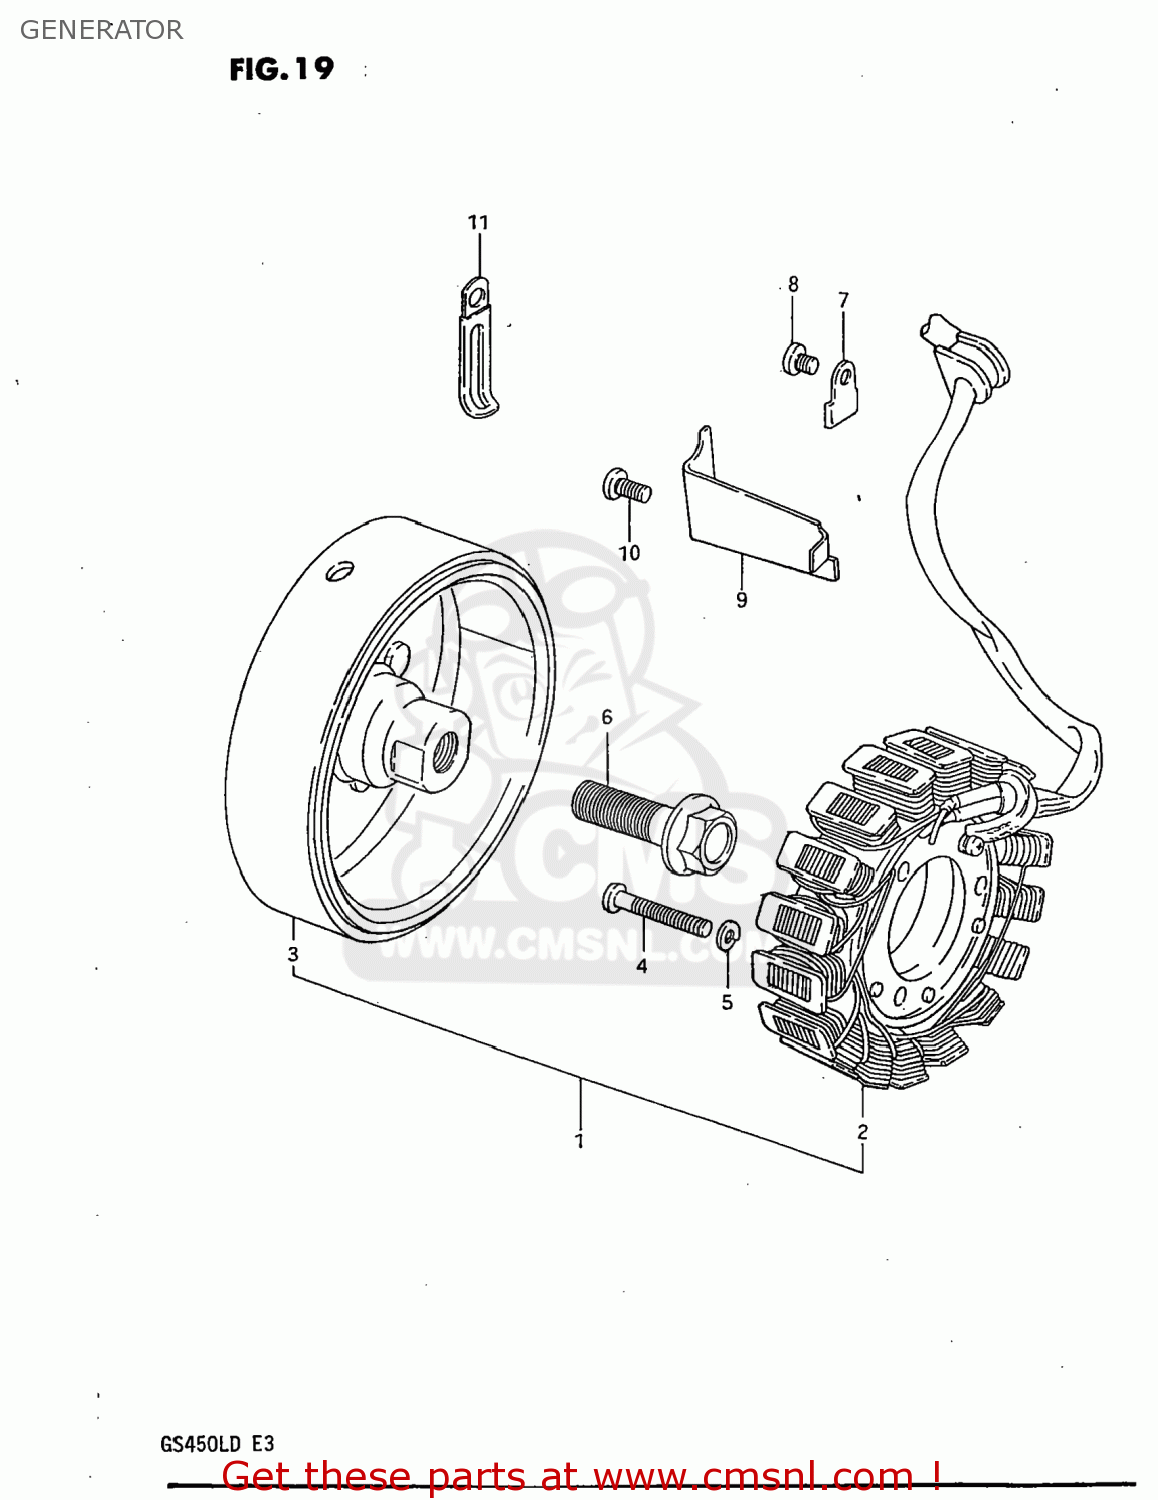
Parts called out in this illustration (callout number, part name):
1	GENERATOR ASSEMBLY
2	STATOR ASSEMBLY
3	ROTOR ASSEMBLY
4	SCREW
5	LOCK WASHER
6	BOLT(12X40)
7	CLAMP,GENERATOR LEAD WIRE
8	SCREW
9	CLAMP,GENERATOR LEAD WIRE
10	SCREW
11	CLAMP L:35
